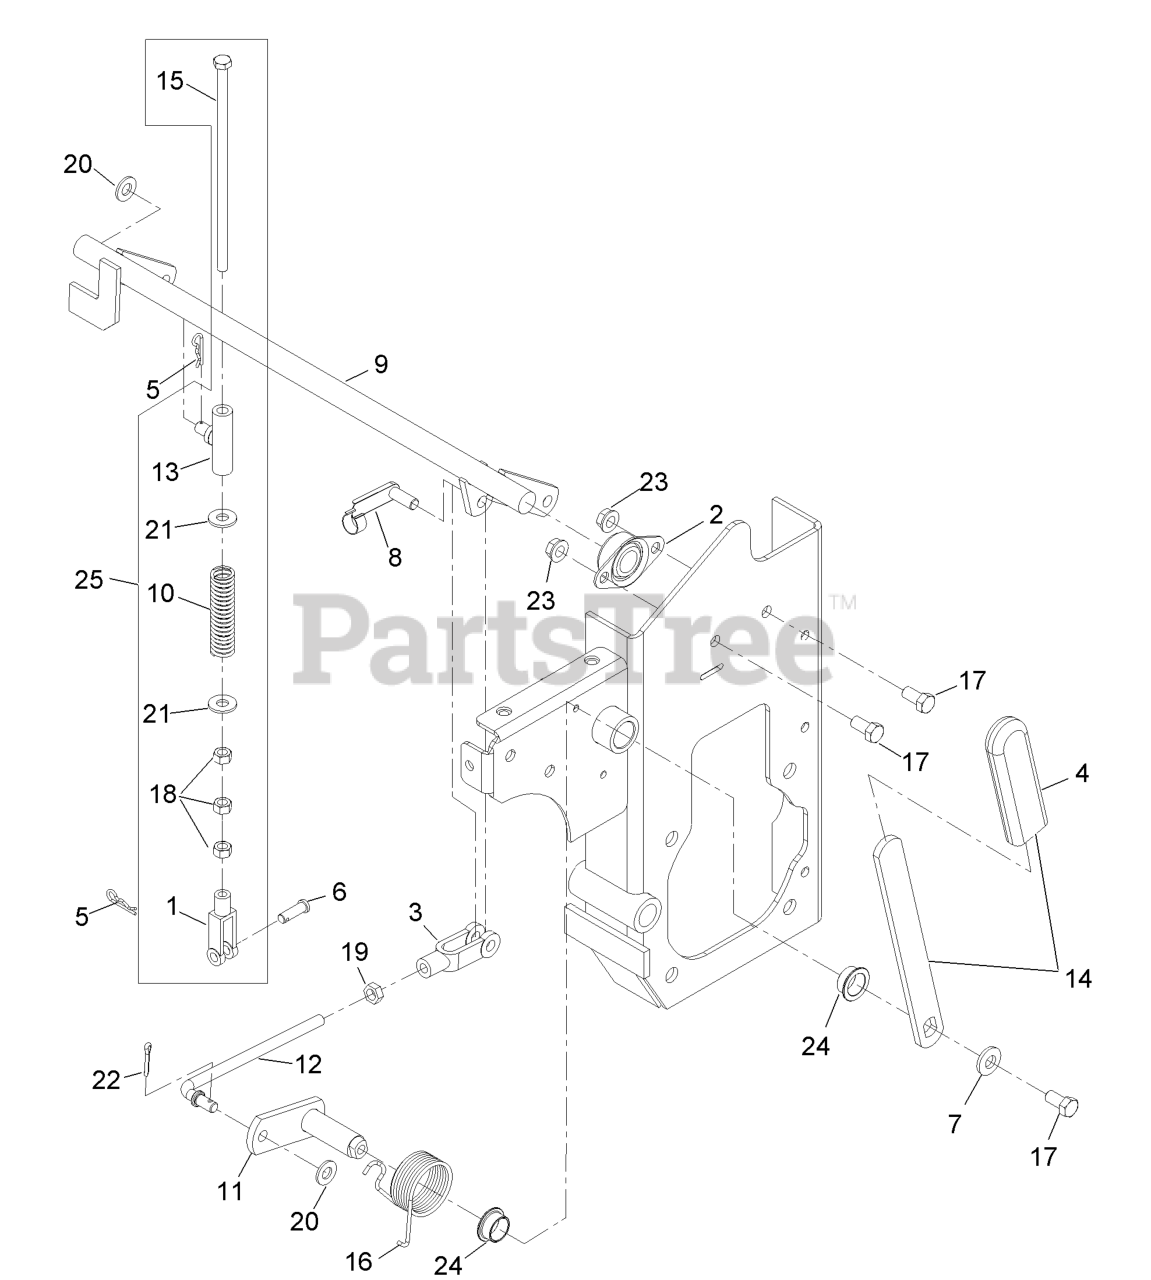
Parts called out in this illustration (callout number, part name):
1	YOKE-ADJUSTABLE
2	BEARING-FLANGE, SIDE
3	YOKE-LINKAGE, BRAKE
4	GRIP-LEVER
5	PIN-COTTER
6	PIN-CLEVIS
7	WASHER-BELLEVILLE
8	PIN-SPRING, CLEVIS
9	WLD, BRAKESHAFT
10	SPRING,COMPRESSION
11	WLD,BRAKE PIVOT (PLATED)
12	ROD,LINKAGE BRAKE (PLATED
13	WLD,SWIVEL BRAKE (PLATED)
14	PARK BRAKE HANDLE ASM
15	SCREW-HH
16	SPRING,TORSION RH
17	SCREW-HH
18	NUT-HEX
19	NUT-HEX
20	WASHER-FLAT
21	WASHER-FLAT
22	PIN-COTTER
23	NUT-HHF, WHIZ
24	BUSHING-BRONZE
25	ASM,BRAKE LINKAGE
